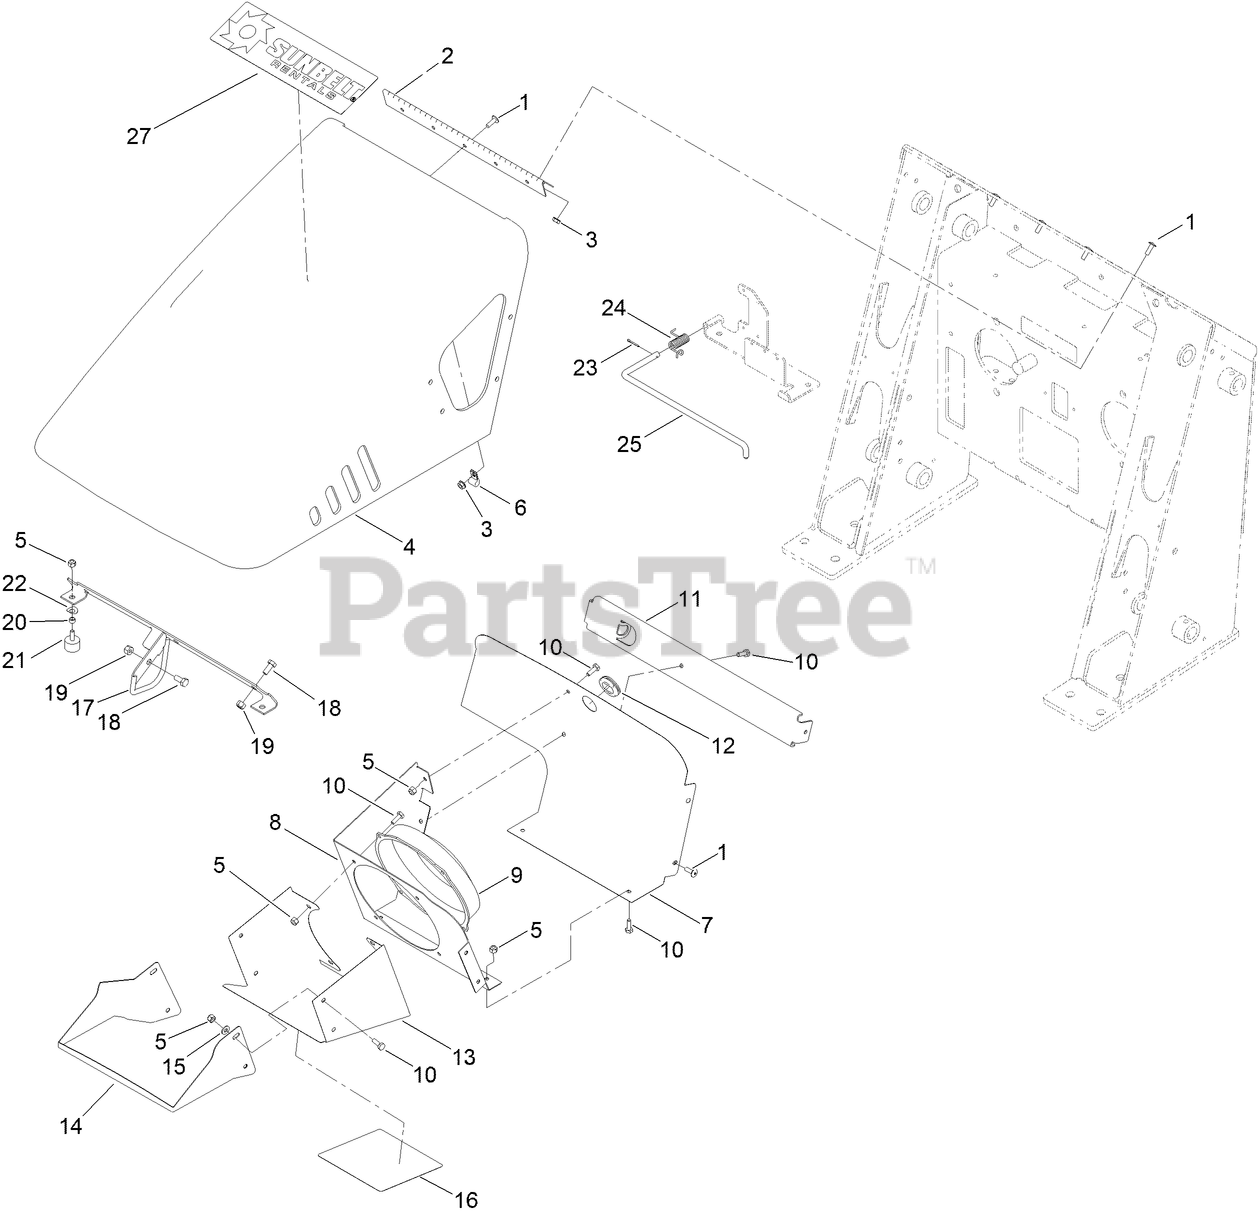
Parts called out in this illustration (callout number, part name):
1	SCREW-HEAD, TRUSS
2	HINGE-HOOD
3	NUT-HF
5	NUT-LOCK, NI
6	CLAMP
7	BRACKET-FAN, BACK
8	BRACKET-FAN, BACK
10	SCREW-HH
11	BRACKET-SUPPORT, HOOD
12	GROMMET
13	SHROUD-FAN
14	SHROUD-FAN, FRONT
15	WASHER-FLAT
16	DECAL-SERVICE TX427 DE
16	DECAL-SERVICE TX427 ES
16	DECAL-SERVICE TX427 FR
16	DECAL-SERVICE TX427 IT
16	DECAL-SERVICE TX427 NE
16	DECAL-SERVICE TX427 PL
16	DECAL-SERVICE TX427 RU
16	DECAL-SERVICE TX427 SK
17	LATCH-ROD
18	SCREW-HH
19	NUT-LOCK, NI
20	SPACER
21	BUMPER
22	WASHER-SPRING
23	PIN-COTTER
24	SPRING-TORSION
25	ROD-SUPPORT, HOOD
27	DECAL-SRHSW4X12
